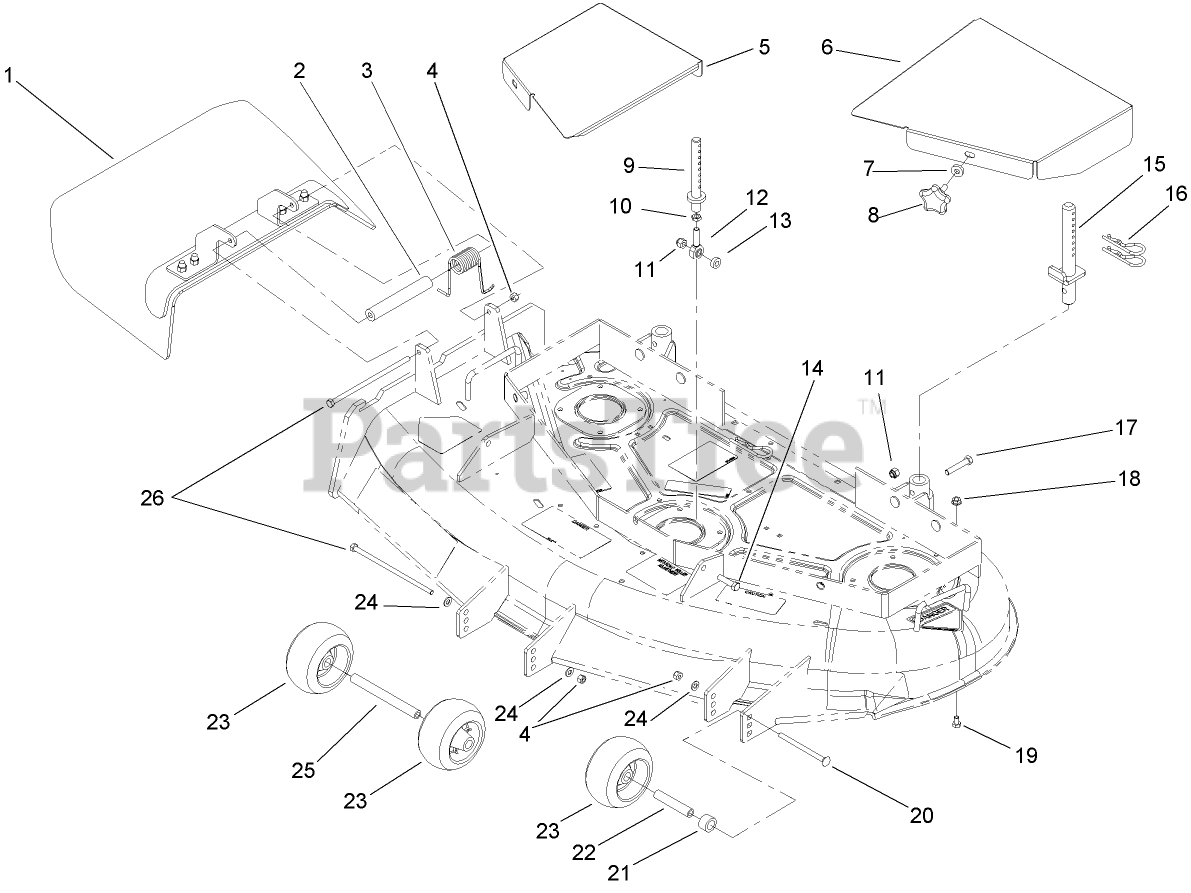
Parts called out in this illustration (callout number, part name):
1	DEFLECTOR ASM
2	SPACER
3	SPRING-TORSION
4	NUT-LOCK, NI
5	COVER-BELT, RH
6	COVER-BELT, LH
7	WASHER-RUBBER
9	FRONT PIN ASM
10	NUT-HJ
11	NUT-LOCK, NI
12	BALLJOINT
13	SPACER
14	SCREW-HH
15	REAR PIN ASM
16	PIN-HAIR
17	SCREW-HH
18	NUT-HF
19	SCREW-HH
20	SCREW-CARR
21	SPACER-WHEEL
22	BUSHING-ROLLER
23	ROLLER-SCALP, ANTI
24	WASHER-PLAIN
25	SPACER-WHEEL
26	SCREW-HH
